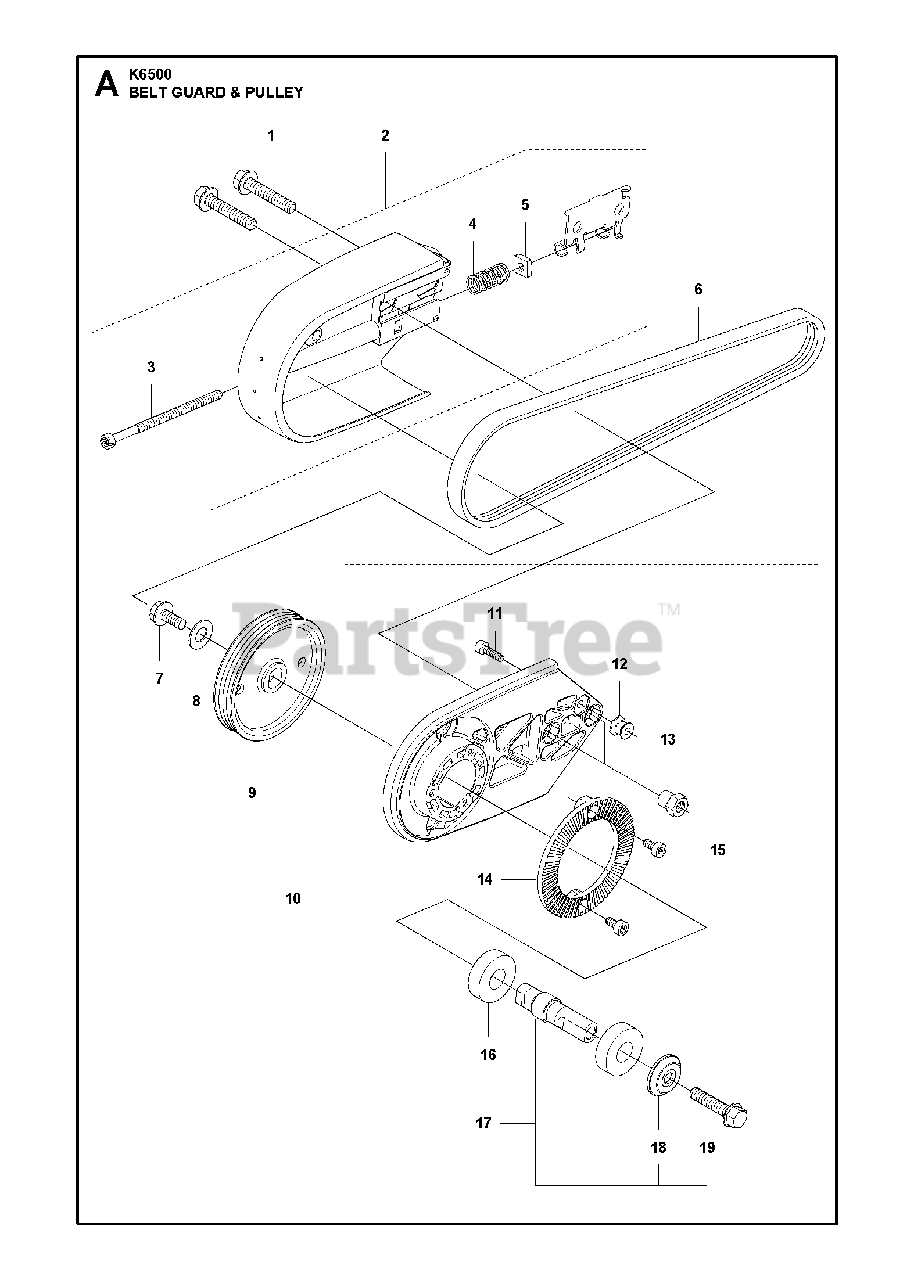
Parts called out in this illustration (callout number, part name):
2	BELT GUARDIncl. 4-6
3	SCREW CITXSCM
4	COMPRESSION SPRING
10	CUTTER HEADIncl. 11-19
11	SCREW ITXSCM
12	TORSION STOP
15	SCREW ITXSCM
16	BALL BEARING
17	SHAFTIncl. 18-19
